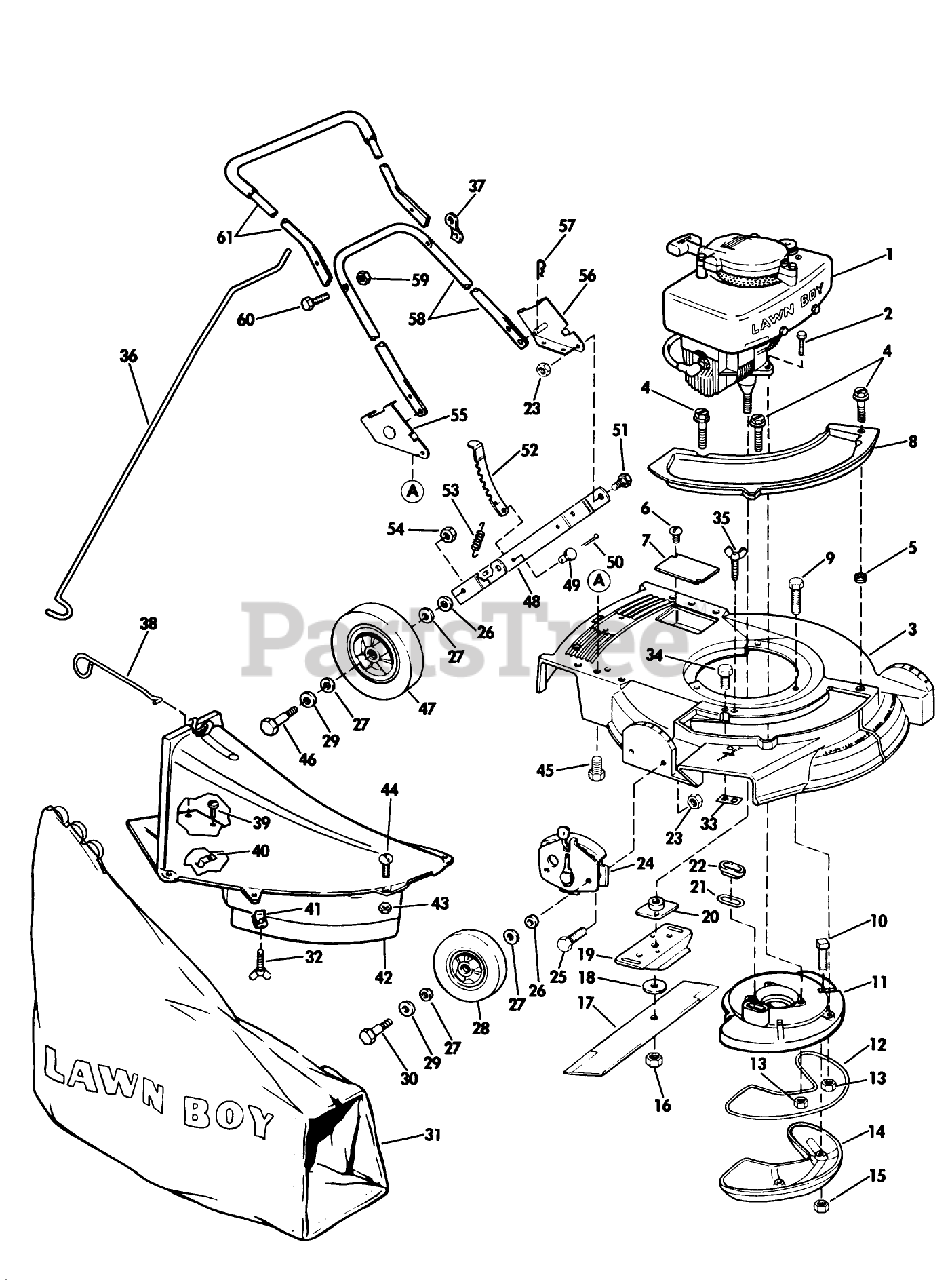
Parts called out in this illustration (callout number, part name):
1	Engine-Model C-18
4	SCREW SEMS TRM HEX HD
15	LOCKNUT E
16	NUT-BLADE
20	PLATE AND COLLAR ASM
21	GASKET S
26	WASHER WROUGHT
30	BOLT WHEEL
31	89802 LB WHOLE GOODS
36	ROD & CLIP
41	SPEED NUT ARDEN
42	Skirt Assembly
51	BOLT-SHOULDER
53	SPRING N.A.S
54	LOCKNUT
57	HAIR PIN
59	Nut-Handle
